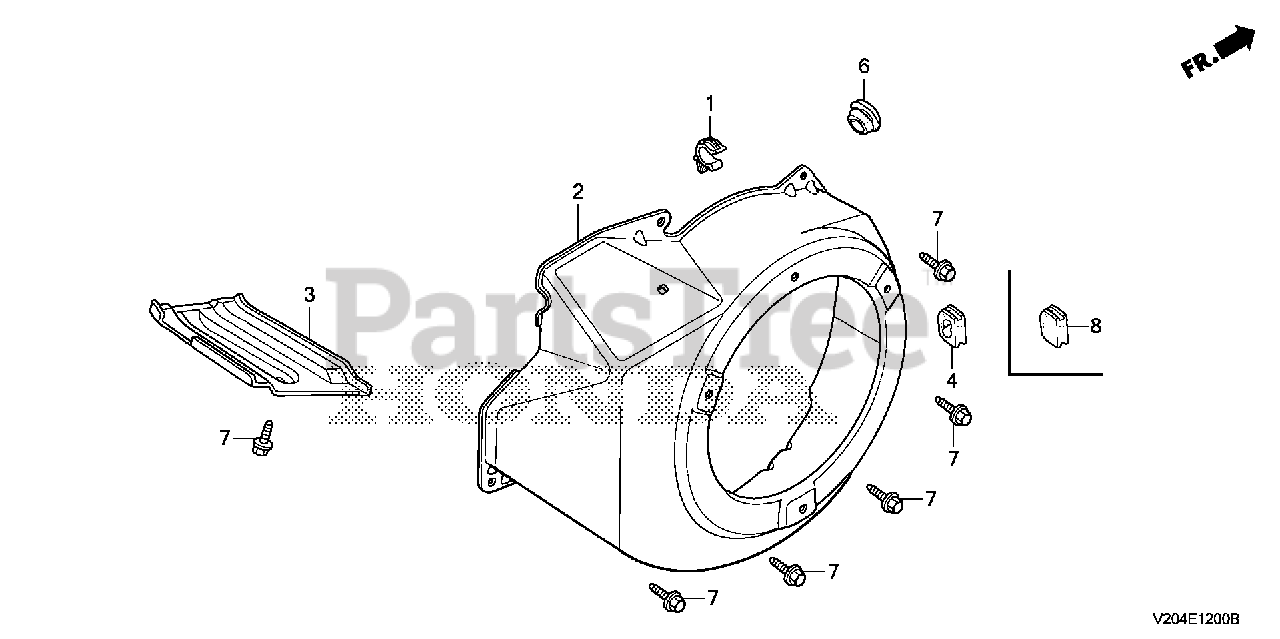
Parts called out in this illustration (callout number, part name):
1	CLIP, TUBE
2	COVER, FAN *R280* (POWER RED)
6	GROMMET, DRAIN HOLE
7	BOLT, FLANGE (6X12) (CT200)
8	GROMMET, WIRE
